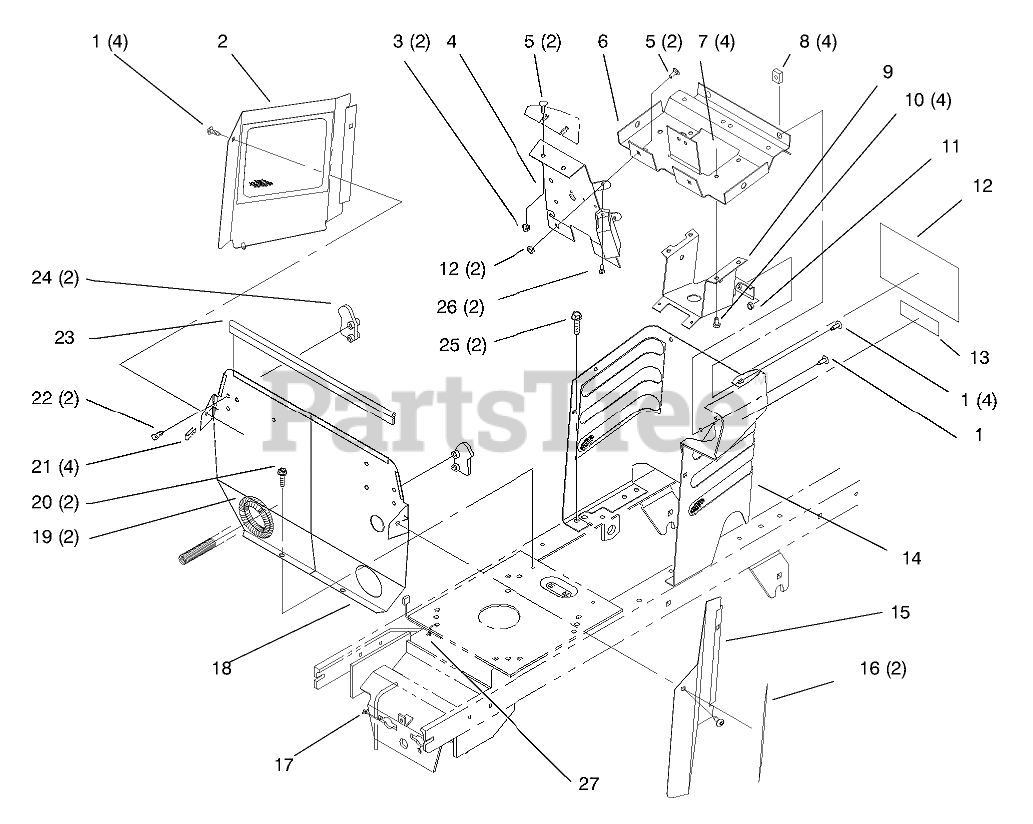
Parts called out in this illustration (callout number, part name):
1	SCREW-HH
2	RH SIDE COVER ASM
3	NUT-KEPS
4	SUPPORT - DASH (BLACK)
5	SCREW-CARR
6	SUPPORT-DASH
7	NUT-HEX
8	NUT RETAINER - J TYPE
9	BRACKET-COLUMN, LOWER
10	SCREW-HH
11	NUT-LOCK, NI
12	DECAL-DANGER
13	DECAL-INSTRUCTION
14	HOODSTAND W/DECALS BLK
15	LH COVER ASM
16	Decal-269-H
18	FIREWALL
19	COVER-SHAFT, DRIVE
20	SCREW-HWH
22	SCREW-PLASTITE
23	TRIM-SEAL, FIREWALL
24	LATCH-HOOD
25	SCREW-HWHTF
26	SCREW-PPHTF
27	TIE-CABLE
